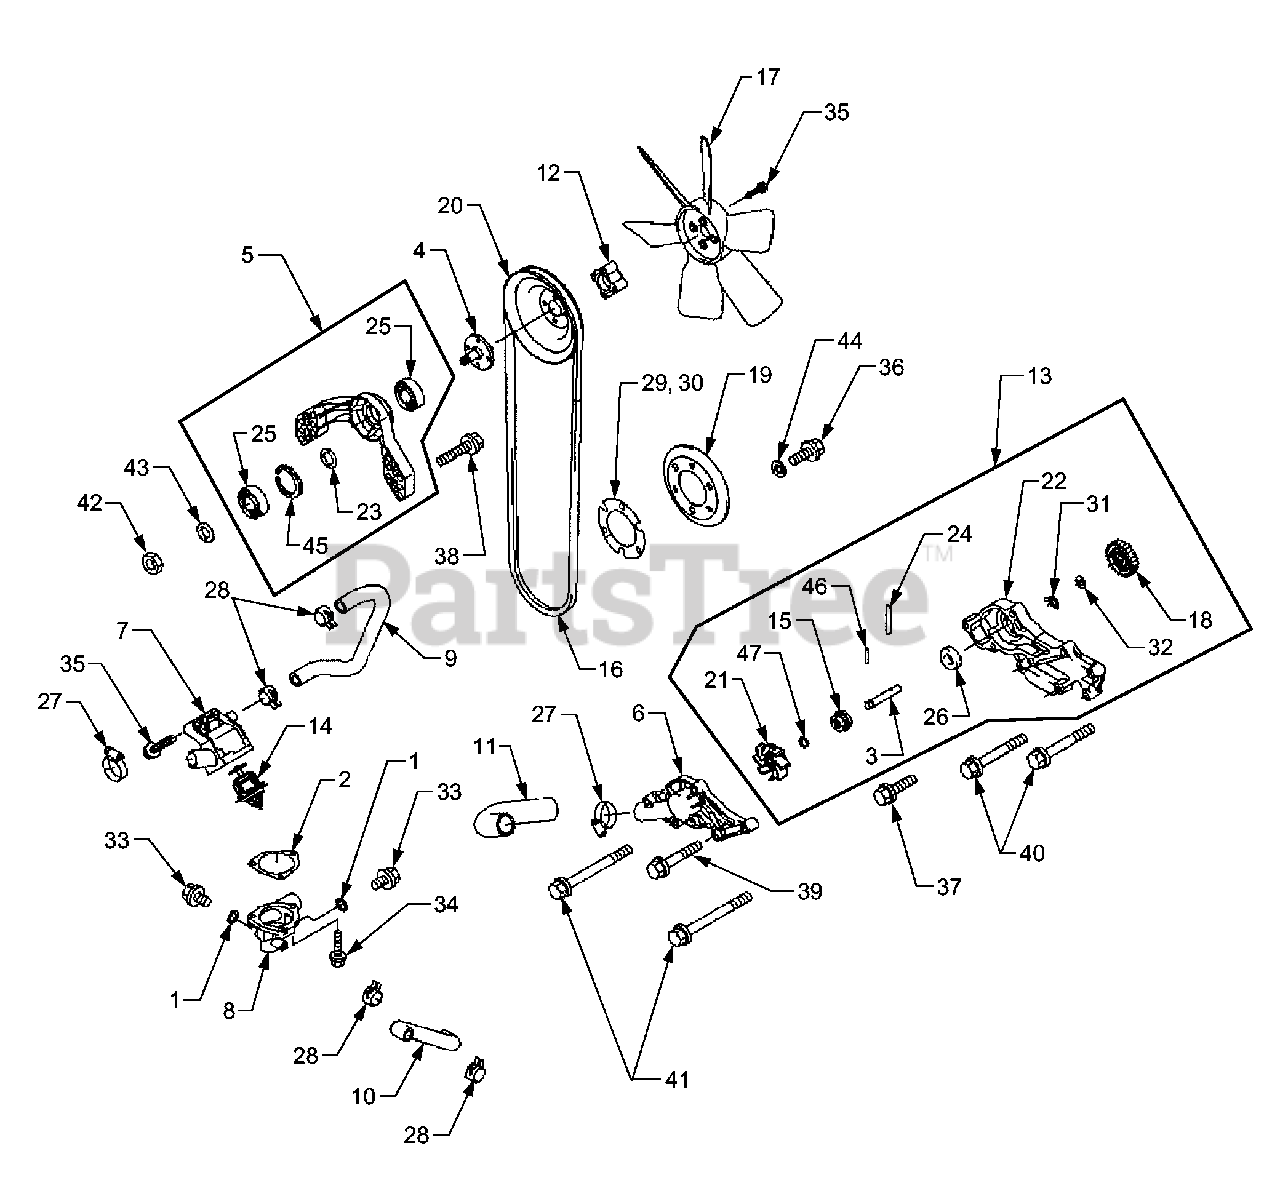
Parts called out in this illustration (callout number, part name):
2	Gasket, Thermostat
3	Shaft, Impeller
4	Shaft, Pulley
5	Housing Assembly
7	Body, Upper
9	Hose, Cooling
10	Hose, Cooling
11	Hose, Cooling
13	Pump Assembly, Water
15	Seal, Mechanical
18	Gear, Spur, 25T
23	Spacer, 12 x 18 x 1.4
25	Bearing, Ball
32	Washer 10.2 x 19 x 0.8
33	Bolt, Flanged
34	Bolt, Flanged
35	Bolt, Flanged
36	Bolt, Flanged
37	Bolt, Flanged
38	Bolt, Flanged
39	Bolt, Flanged
40	Bolt, Flanged
41	Bolt, Flanged
42	Nut, Hex Fine
43	Washer, Plain
44	Washer, Spring
